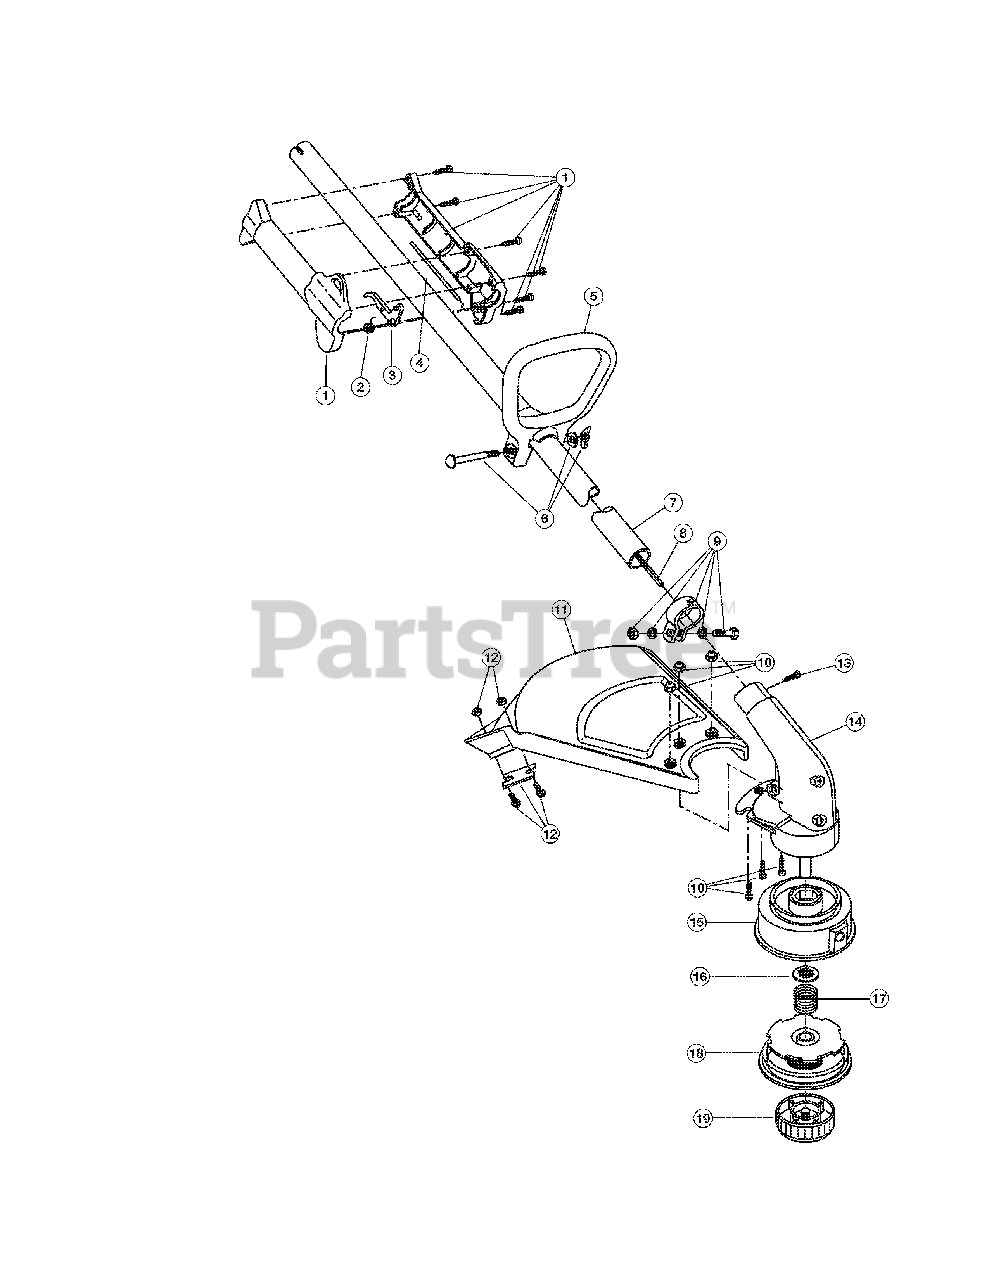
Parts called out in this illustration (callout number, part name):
1	Throttle Housing Assembly (includes 2 & 3)
2	Throttle Trigger Spring
3	Throttle Trigger
4	Throttle Cable
5	D-Handle (includes 6)
6	D-Handle Hardware
7	Drive Shaft Housing
8	Flexible Drive Shaft
9	Lower Clamp Assembly (includes 13)
10	Guard Mounting Screw Assembly
11	Guard Assembly (includes 12)
12	Blade Assembly
13	Anti-Rotation Screw
14	Gearbox Assembly (includes 15)
15	Outer Spool Assembly (includes 16)
16	Retainer
18	Inner Reel
19	Bump Head Knob Assembly
